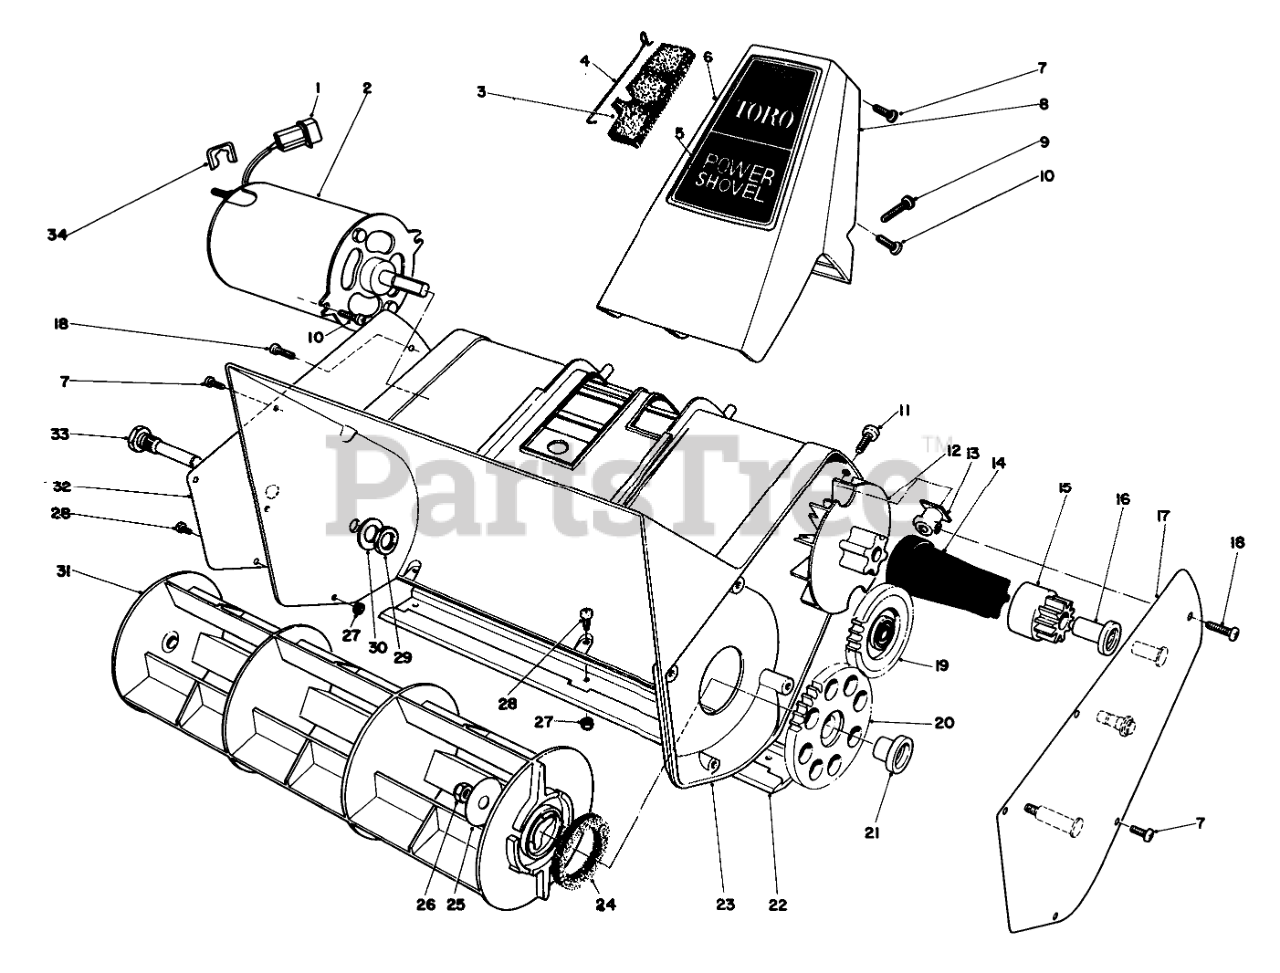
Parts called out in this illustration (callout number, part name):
1	Pin Housing
2	ELEC MOTOR
3	FOAM FILTER
4	RETAINER - FILTER
5	HANDLE SUPT DECAL
6	HANDLE SUPPORT, FRONT
7	SCREW-PPH
8	Handle Support-Back
9	SCREW-PPH
10	SCREW-PPH
11	SCREW-PPH
12	FAN, POWER SHOVEL
13	MOUNTING BLOCK
14	DRIVE COUPLING
15	Drive Gear (Incl. Ref. #16)
16	BUSHING, DRIVE GEAR
17	Gear Carrier
18	Screw
19	Idler Gear Assembly
20	Rotor Gear Assembly (Incl. Ref. #20)
21	BUSHING, ROTOR GEAR
22	Scraper
23	H.S. HOUSING-CSA
24	FELT WASHER
25	ROTOR WASHER
26	NUT-LOCK, NI
27	NUT-LOCK
28	SCREW-PPH
29	NUT-HEX
30	WASHER-FLAT
31	ROTOR
32	RT. SIDE COVER (RAW)
33	ROTOR PIN
34	Strain Relief
